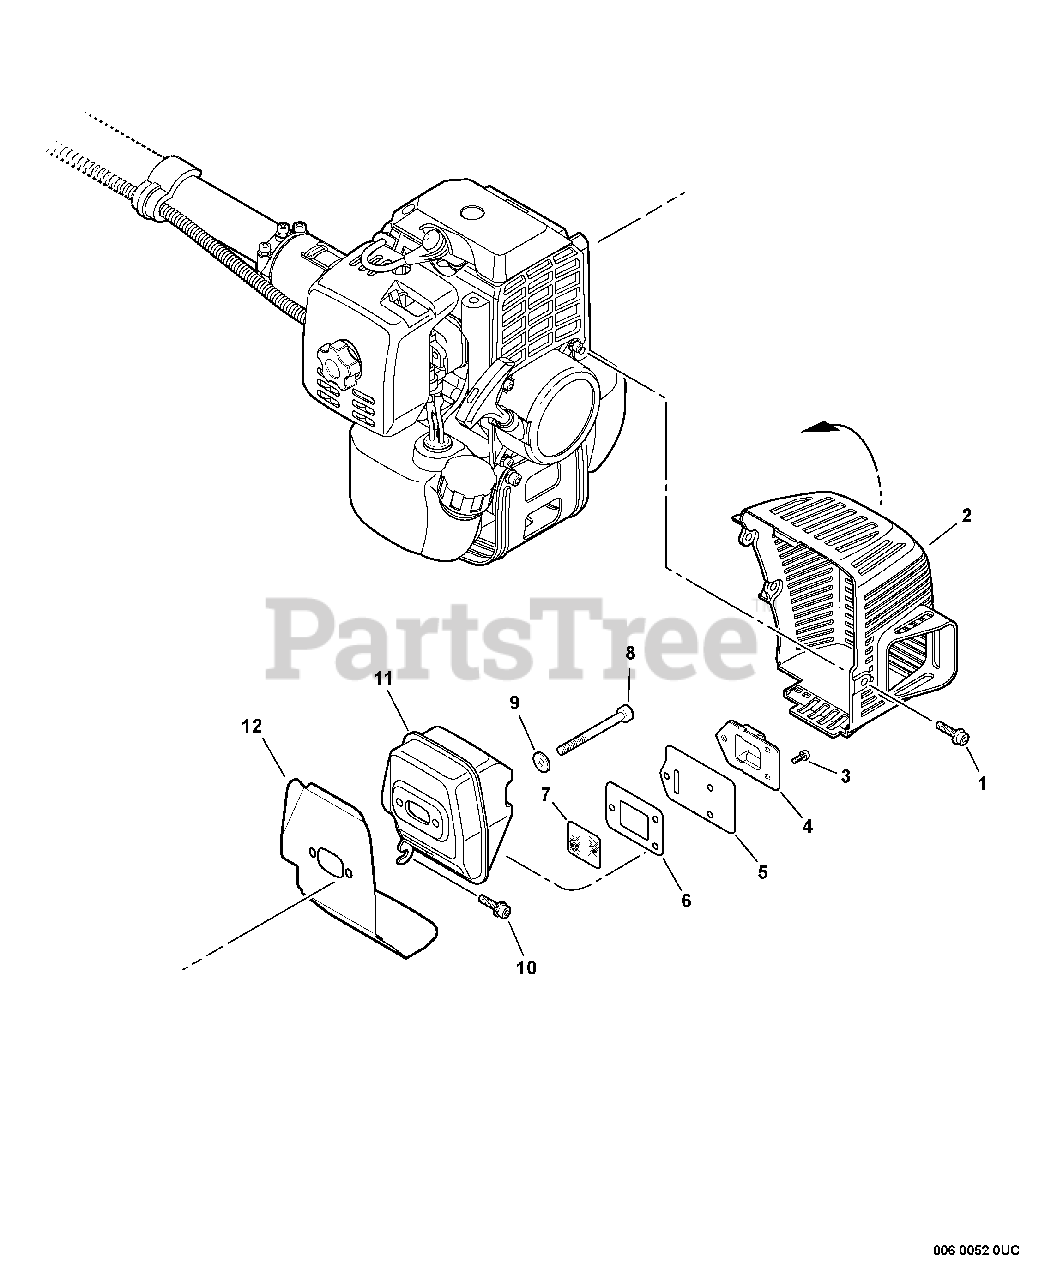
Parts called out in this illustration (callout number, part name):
1	SCREW - 5X14
2	COVER, EXHAUST
3	SCREW - 4X12
4	GUIDE, EXHAUST
5	GASKET, EXHAUST
6	GASKET, EXHAUST
7	SCREEN, SPARK ARRESTOR
8	SCREW - 5X60
9	WASHER - 5
10	SCREW - 4X10
11	MUFFLER
12	SHIELD, EXHAUST
